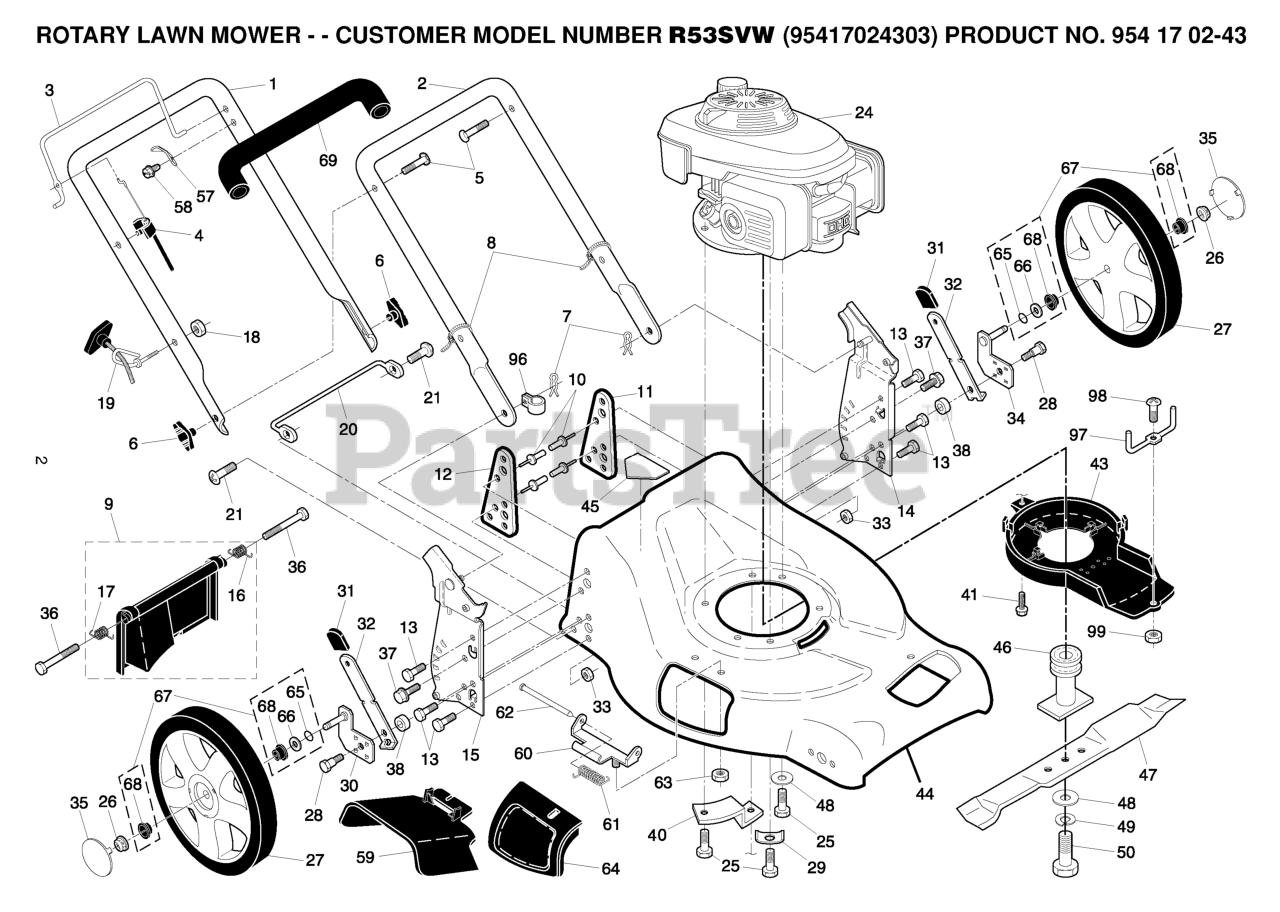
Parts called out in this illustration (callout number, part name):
2	LOWER HANDLE
3	BAIL, FLAT AUTO WALK
4	CABLE.ENGINE BRAKE.MZR
5	BOLT, HANDLE 5/16-18X1.75
6	KNOB, DEFLECTOR
7	HAIRPIN COTTER
8	TIE GUIDE
9	KIT.DOOR.RR.ASM.21.FWGD
10	RIVET BLIND
11	SUPPORT BRACKET LH
12	SUPPORT BRACKET RH
13	SCREW 14-20 X 5/8
14	BRKT.ASM.HNDL.21FGD.EZ
15	BRKT.ASM.HNDL.21FGD
17	SPRING.REAR.DOOR.EZ.21
18	NUT
19	ROPE, GUIDE
25	BOLT 3/8-16X1-1/8
26	HEX FLANGE LOCKNT
27	RP WHEEL 14X2
28	SHOULDER BOLT
29	WASHER.ENGINE.BZP
30	AXLE ARM ASSEMBLY RR
31	KNOB.EXT.ERGO.BLACK
32	SELECTOR SPRING
33	NUT.71038.31-18.HEX.NYLOCK
34	AXLE ARM ASSEMBLY LR
35	HUBCAP
37	SELF-TAPPING SCREW 5/16-18X3/4
38	WASHER.FLAT.34X1.38X22
40	BRACKET
41	SCREW.HEX.WSH
43	DEBRIS SHIELD
45	DECAL.INTERNATIONL.CUTFINGER
46	RP ADAP.BLDE/PULL
47	21" PUSH BLADE
48	WASHER,HARDEN
49	LOCKWASHER
50	SCREW, HEX HD 3/8-24 X 1-3/8
57	BRACKET UPSTOP
59	DEFLECTOR.CLIPPIN.21.FGD
60	BRACKET.ASM.HINGE.21.FWGD.
61	SPRING.TORSION
62	ROD.HINGE.21
63	LOCKNUT.NYLOC.1/4-20
64	DOOR.MULCH.21.REAR.FWGD
65	O-RING
66	WASHER.FLAT.1/2
67	KIT.BUSHING.WHEEL.14"
68	Bushing, Nylon, Black
69	GRIP.HANDLE.FOAM.WIDE.(1 SIDE)
96	CLIP.CABLE.BLK
97	KEEPER.BELT.FGD
98	SCREW.#8.MACH
99	NUT.HEX.#8
